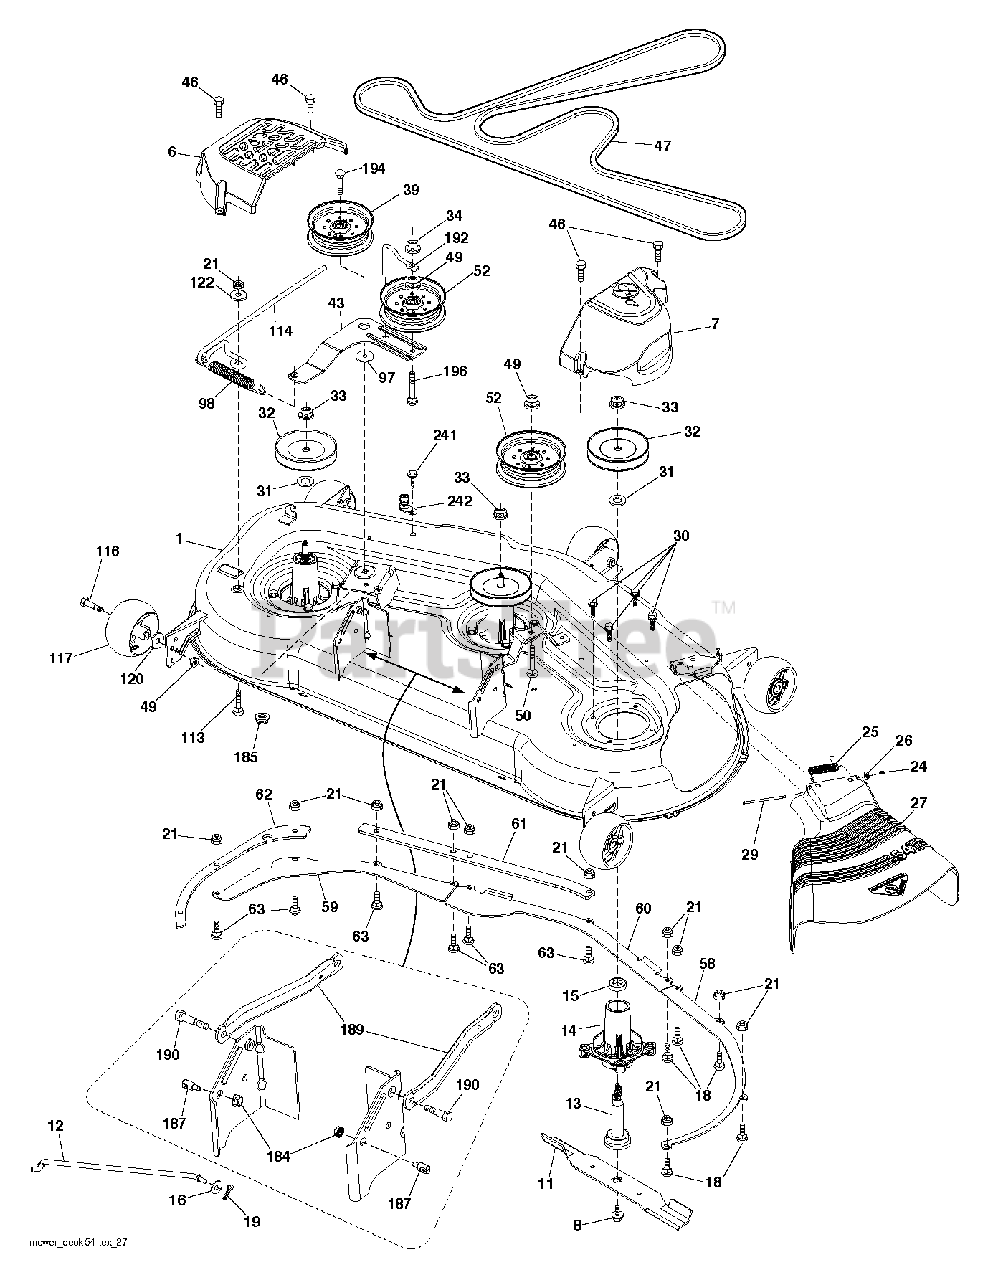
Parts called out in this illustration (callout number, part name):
1	DECK.WELDMENT.54'
6	COVER.MANDREL.LH.54"20
7	COVER.MANDREL.RH.54.20
8	BOLT.WASHER.ASM.7/16-2
11	BLADE.BAGGING.54"
12	ROD.ANTI.SWAY.48/54"K4
13	SHAFT ASM MANDREL
14	HOUSING.MANDREL.4PT.
16	WASHER
18	BOLT
19	PIN.COTTER.5/16.BOW TI
21	LOCKNUT
24	CAP-SLEEVE LT
25	SPRING, TORSION
26	NUT PUSH M
27	DEFLECTOR
29	ROD.HINGE
30	SCREW, WASHER HEAD
31	WASHER.SPACER.MANDREL
32	PULLEY/MANDREL
33	NUT.FLANGE.LOCK.TOP
39	RB PULLEY.IDLER.4.50/HUB SPEC
46	SCREW.1/4-20X5/8
47	BELT.DRIVE.54."2006
49	NUT LOCK FLG 3/8-16 UNC
52	PULLEY.IDLER.2006
58	BAFFLE.RIGHT.54"
59	BAFFLE.LEFT.54"
60	BAFFLE CENTER 54" MOWER
61	PLATE.REINFORCE.54.FRONT.X498
62	PLATE.REINFORCE.54.SIDE.X498
63	BOLT.CARRIAGE.5/16-18
98	SPRING, DECK DRIVE
114	ROD TENSION RELIEF
116	BOLT.SHOULDER.3/8-16X3-5/8.
117	WHEEL. GUAGE RALLY
120	WASHER
122	BUSHING.RELIEF.TENSION
184	NUT LOCK HEX FLANGE 5/16-18
185	NUT.LOCK.FLANGE.7/16
187	STUD.FASTNER.W/ANTI-ROTATE
189	ARM.SUSPENSION.MOWER
190	BOLT.SHOULDER
192	KEEPER.BELT.IDLER.54"T
194	BOLT.HEX.WASHER.HEAD.7/16-24X
241	SCREW.TT.#10-32X.5.3/8.FLANGE
242	PORT.WASHOUT
